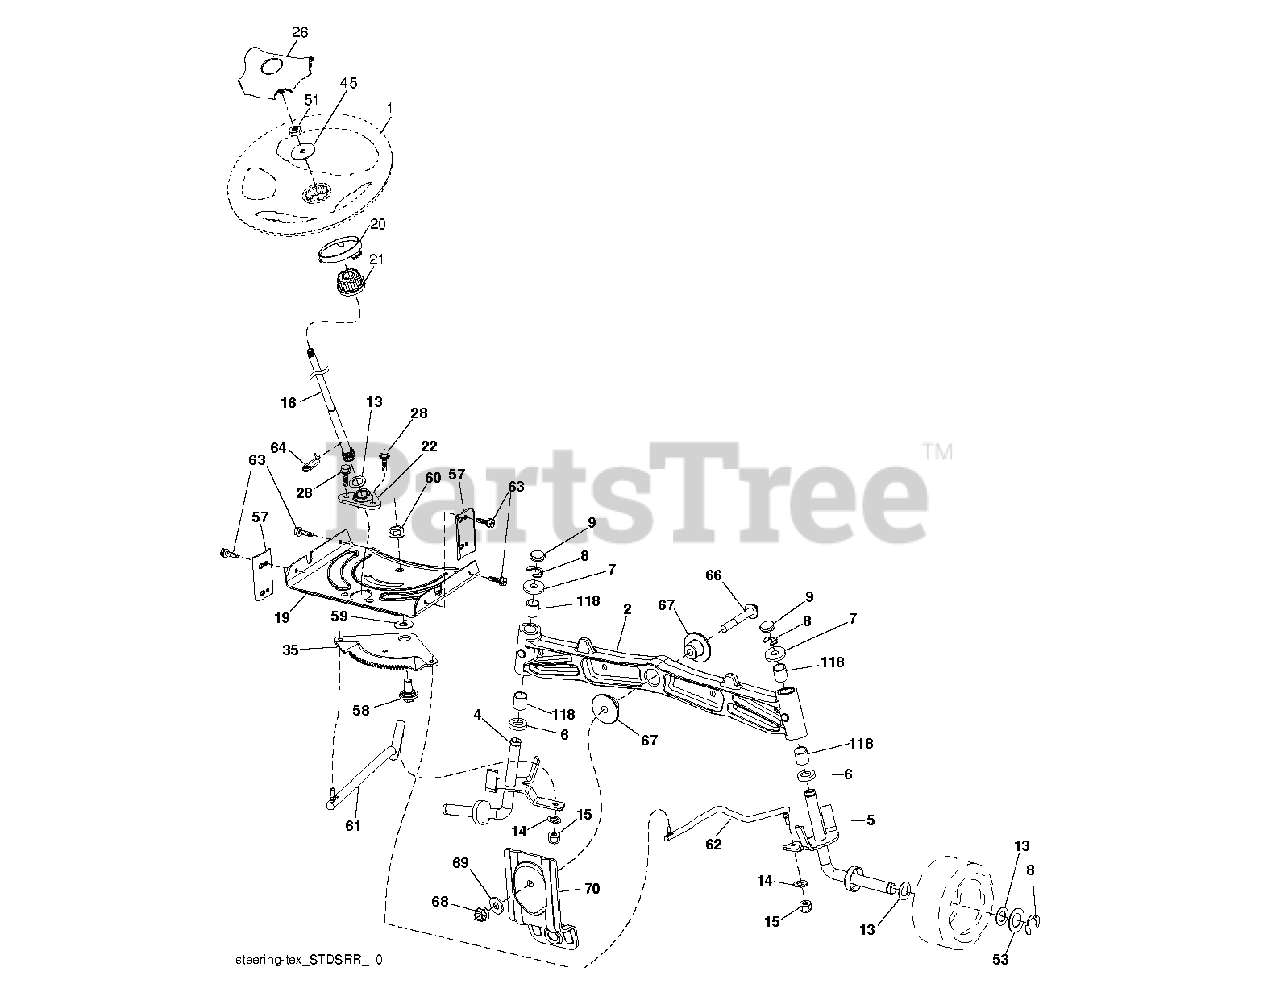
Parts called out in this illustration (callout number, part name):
1	WHEEL.STEERING.STDSRR.BLK/OV
2	AXLE.SVC.ASM CAST IRON.TEX
4	SPINDLE.WELDED.LH.15"TEX
5	SPINDLE.WELDED.RH.15"T
8	RING CLIP
9	CAP.SPINDLE
14	WASHER, LOCK 3/8
15	NUT CROWNLOCK 3/8-24
16	SHAFT.STEER.STEALTH.DD
19	PLATE.STEER.DDL.NLT/NG
21	ADAPTER, WHEEL STNG..
22	BUSHING.ASM.STEERING.A
26	CAP.WHL.STRNG.STDSRRD.SRS.BLK
28	SCREW, 3/8-16X3/4
35	GEAR.SECTOR.PLATE.DDL.
45	WASHER 9/16"ID, 2 3/8"OD
51	NUT.HEX.1/2-20
53	WASHER.HARDENED
57	BRACKET.UPSTOP.TEX
58	BOLT.SHOULDER.SECTOR.P
59	WASHER.THURST.SECTOR.S
60	NUT FLANGE LOCK 5/8-11
61	DRAGLINK.LH.BALLSTUD.D
62	DRAGLINK.RH.BALLSTUD.D
63	SCREW
64	RETAINER.CLIP.SPRING.S
66	BOLT HEX FGHD 7/16-14 X 3 SERR
67	BUSHING.PM.FRONT AXLE
68	NUT.LOCK.FLANGE.7/16
69	WASHER.1.5X.505X.118
70	BRKT.DECK.SUSPENSION.F
118	BUSHING, AXLE CAST
